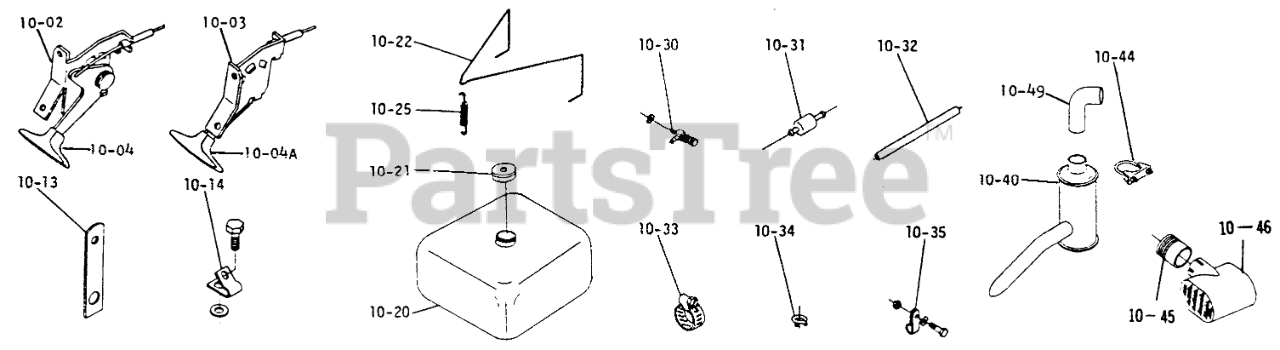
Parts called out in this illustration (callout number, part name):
10-03	THROTTLE CONTROL
10-04	KNOB-CHOKE
10-04A	KNOB-THROTTLE
10-14	THROTTLE CONTROL CLP
10-22	HOLD DOWN WIRE
10-30	S/A FUEL VALVE
10-40	MUFFLER
10-44	ASSY-MUFFLER CLAMP
10-46	MUFFLER
